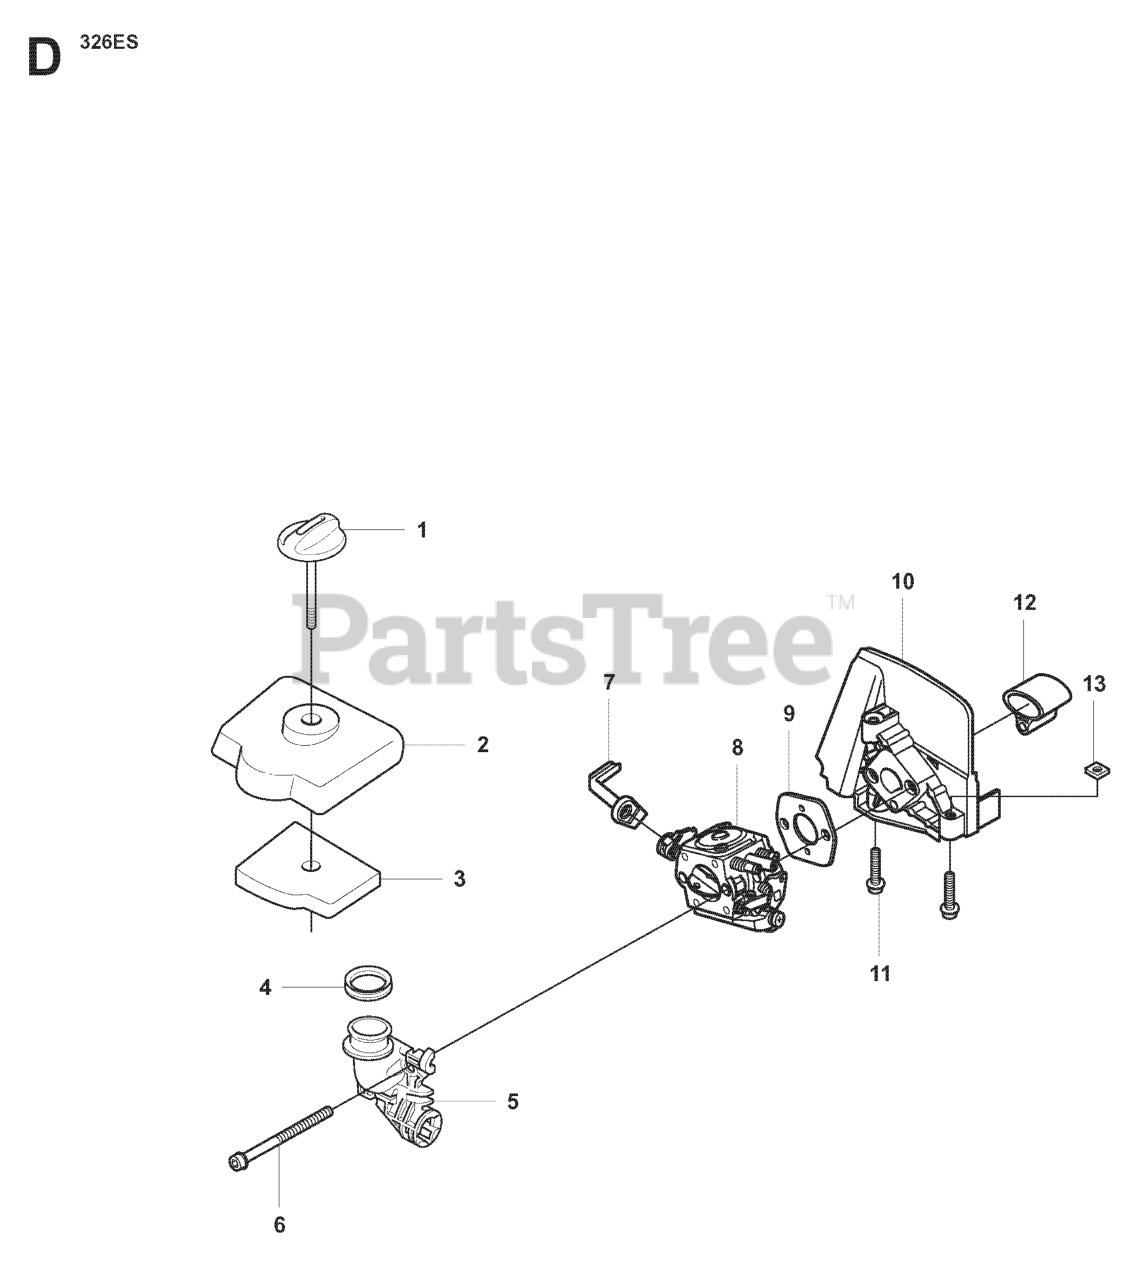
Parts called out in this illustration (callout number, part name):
2	FILTER COVER
3	AIR FILTER
7	CHOKE CONTROL
8	CARBURETOR
